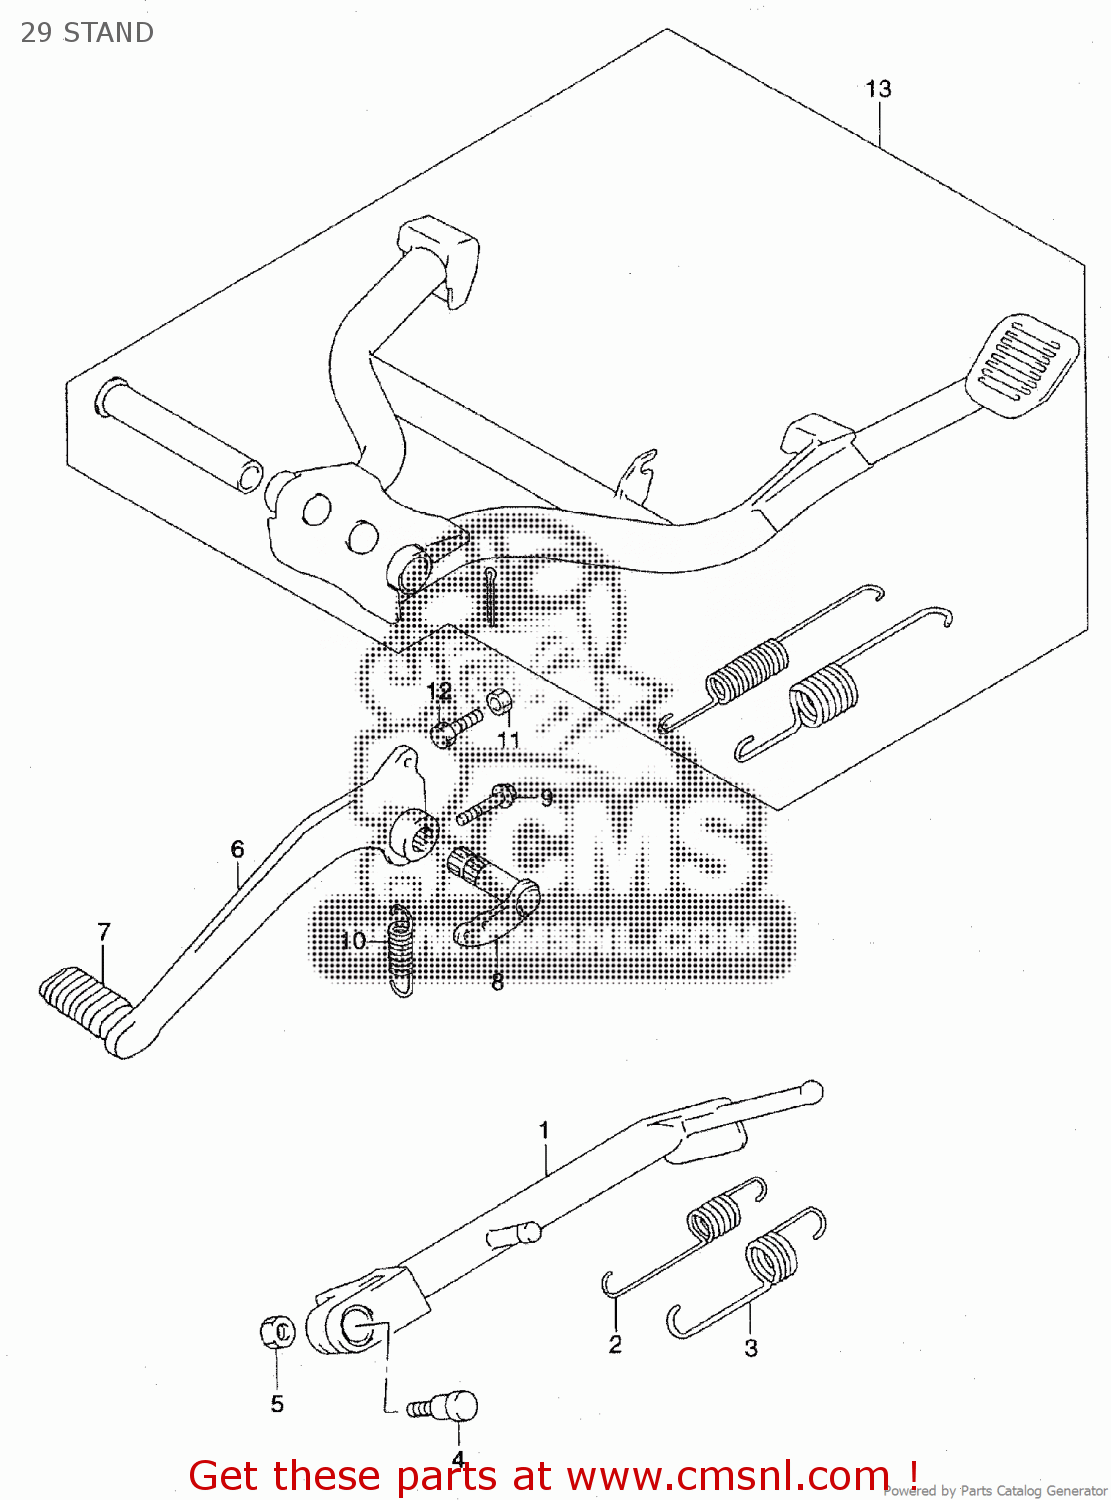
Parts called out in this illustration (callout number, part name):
2	SPRING
3	SPRING
4	BOLT(10X34)
5	NUT
6	PEDAL,BRAKE
7	RUBBER,PEDAL
9	BOLT
10	SPRING
11	NUT 6MM
12	BOLT(6X23)
13	STAND SET,CTR
